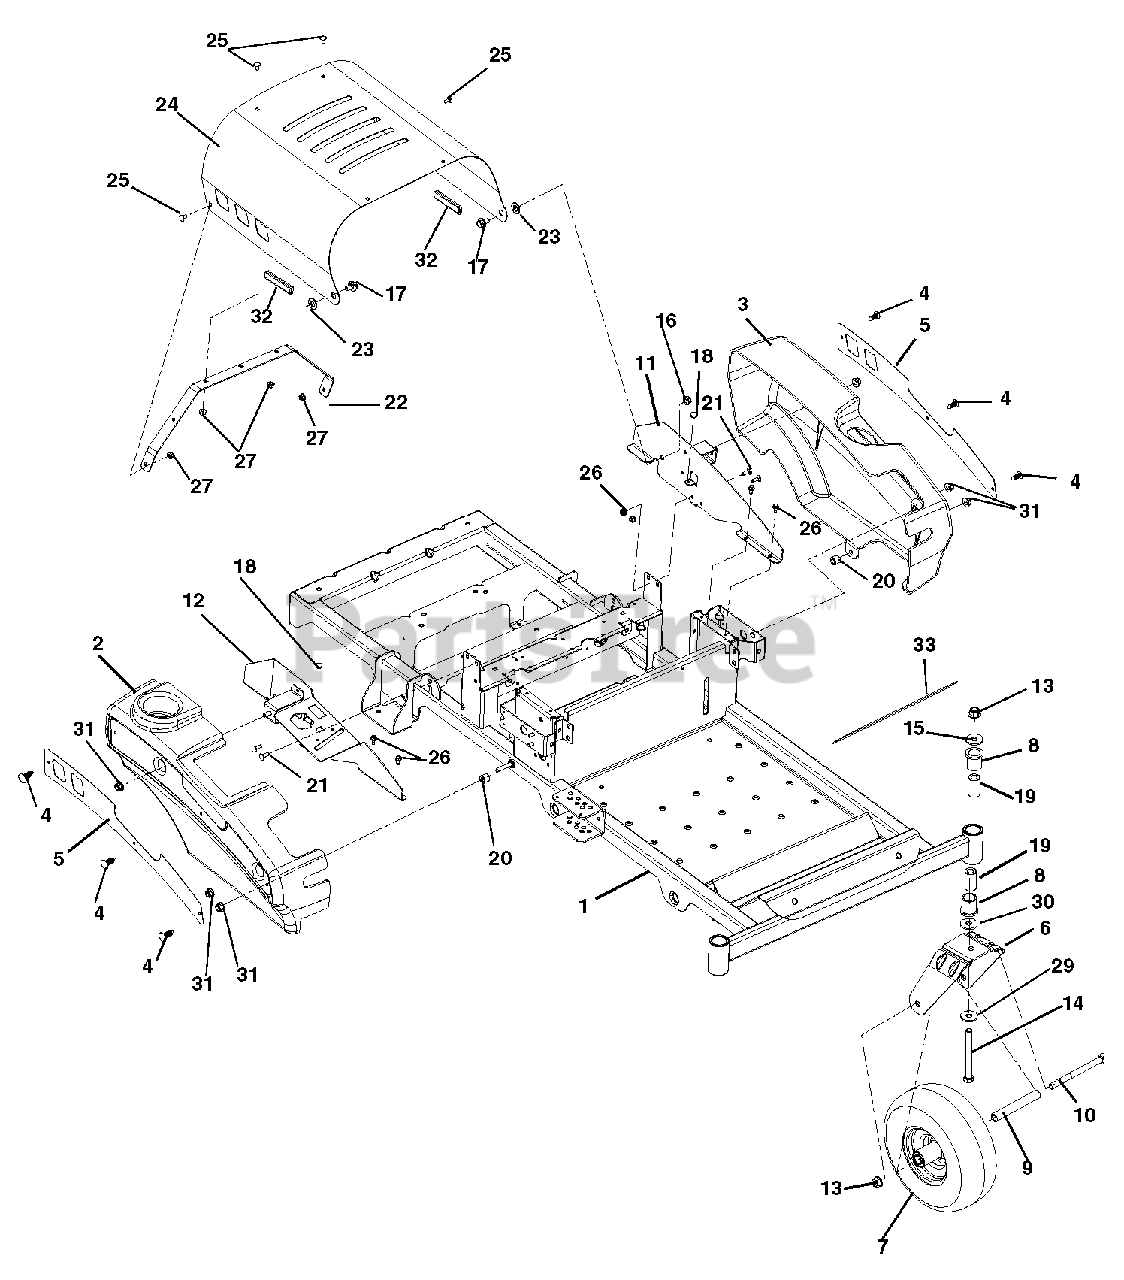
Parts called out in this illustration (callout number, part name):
1	Weldment, Frame
2	Fender, Right Hand
3	Fender, Left Hand
4	Rivet, Nylon
5	Plate, Fender
6	Fork, Caster
7	Wheel/Tire Assembly, 11.0 x 4.0 x 5.0
8	Bushing, Flange 1.00 x 1.25 x 1.50 x 1.50
9	Spacer, Wheel
10	Bolt, Hex .50-13 x 6.50 Grade 5
11	Weldment, Fender Mount Right Hand
12	Weldment, Fender Mount Left Hand
13	Nut, Locking-Top-Flange .50-13
14	Bolt, Hex .50-13 x 5.00 Grade 5
15	Washer, Flat Steel .511 x 1.441 x .125
16	Nut, Locking-Top-Flange .38-16
17	Bolt, Shoulder .375-16 x .135
18	Bumper Grommet .125 x .250 Diameter
19	Spacer, Caster
20	Bushing, Sleeve .391 x .688 x .52
21	Bolt, Round Head Square Neck .25-20 x .75 Grade 5
22	Hood Brace
23	Washer, Flat-Nylon .52 x 1.00 x .08
24	Hood, ZT
25	Bolt, Round Head Square Neck .25-20 x .50 Grade 5
26	Nut, Locking Nylon Flange .25-20
27	Screw, Tapping .25-20 x .50 Hex Washer Head Thread
29	Washer-Flat-Steel .515X1.625X.250
30	Washer-Flat-Steel .518X2.0X.105
31	Nut, Locking-Nylon-Flange .31-18
32	Edging, Clutch Paddle - 2.00"
33	Grip, Adhesive (1" x 16" BLK)
